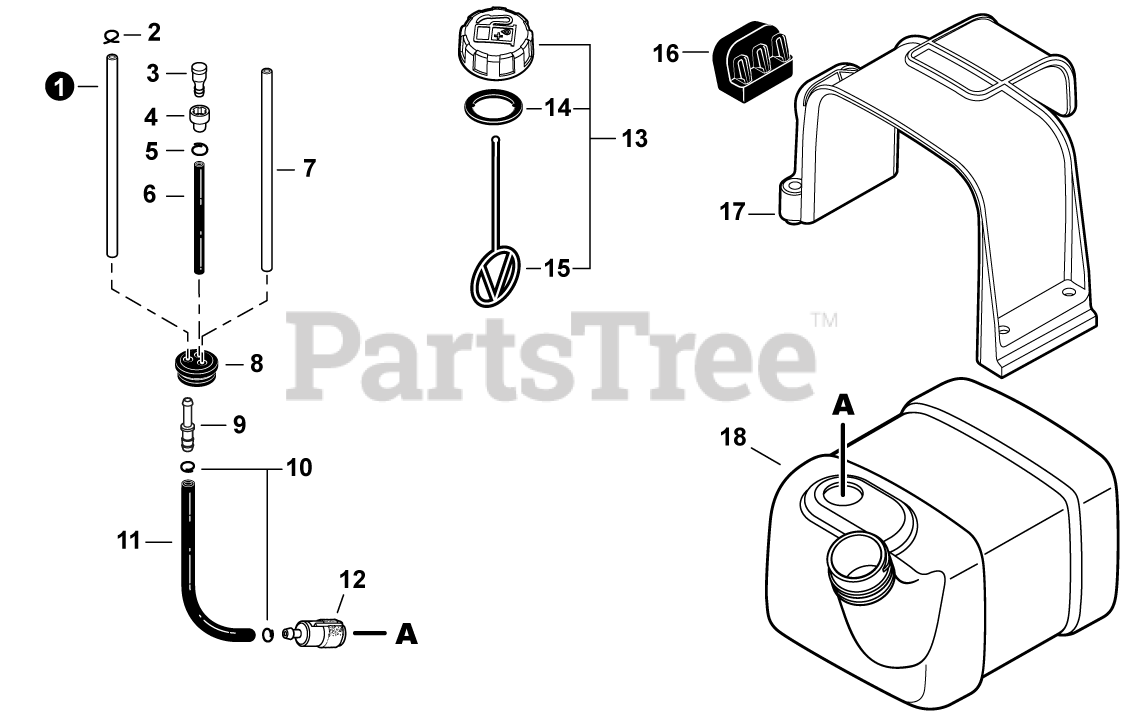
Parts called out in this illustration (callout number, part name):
1	PIPE, FUEL 3.5x6x205 CLEAR
2	CLIP, SPRING 5.2
3	VENT ASSY
4	HOLDER, VENT
5	CLIP 6.5 MM
6	PIPE, FUEL 3x6x40 BLACK
7	PIPE, FUEL 3x6x180 YELLOW
8	GROMMET, FUEL
9	CONNECTOR, PIPE 5x3.5
11	PIPE, FUEL 3x5x120 BLACK
12	FILTER, FUEL
13	CAP ASSY, FUEL
14	GASKET, FUEL CAP
15	CONNECTOR, CAP L= 100 MM
16	CUSHION
17	RETAINER, FUEL TANK
18	TANK, FUEL
